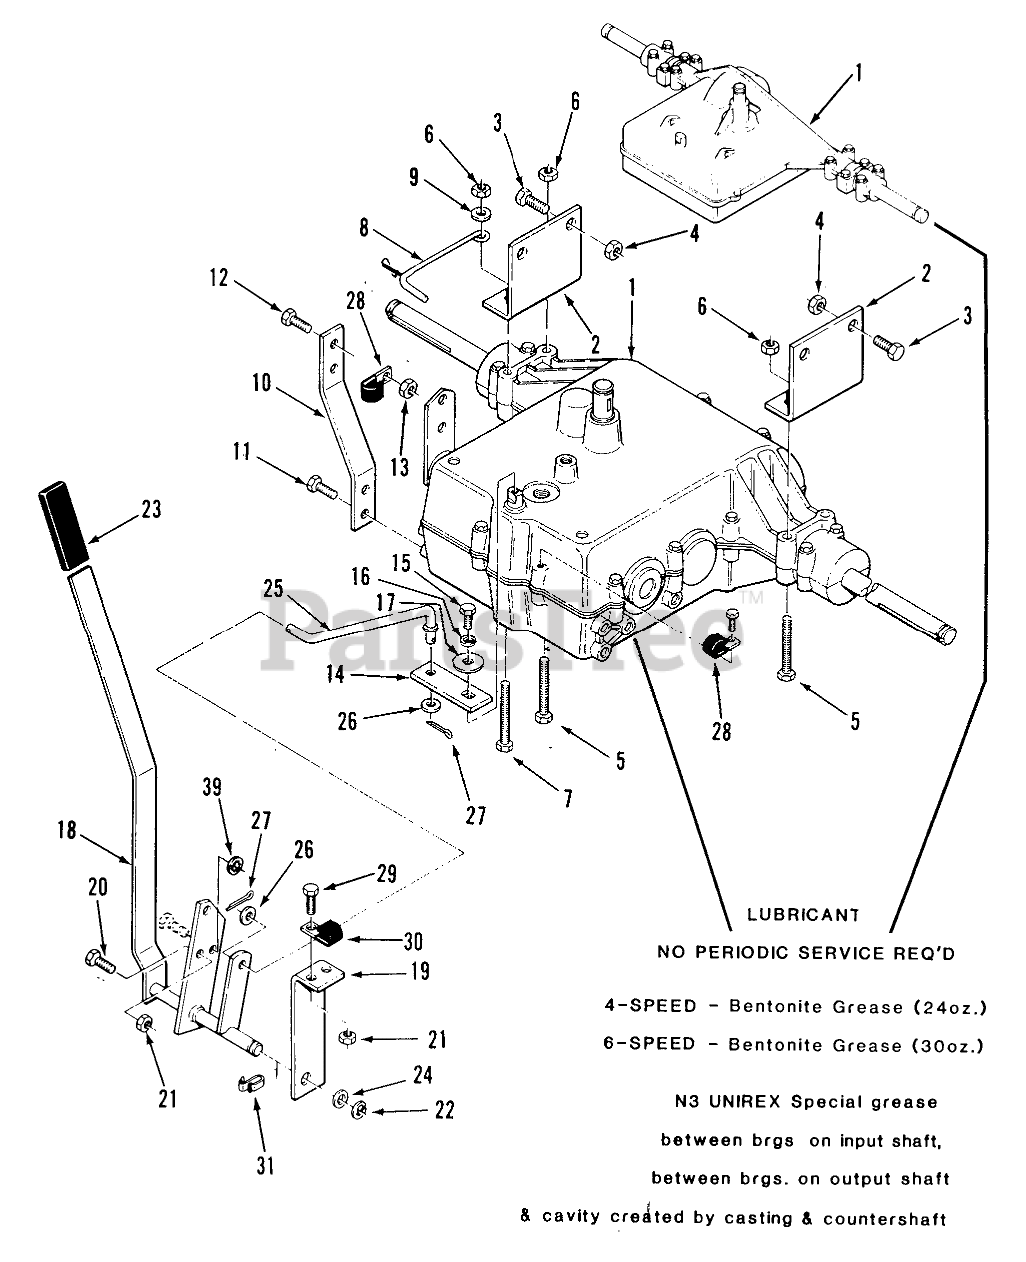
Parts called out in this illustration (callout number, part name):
1	Peerless Transmission (900-028) 110-4 Only
2	Bracket-Rear Axle
3	BOLR HWH 3/8-16X7/8
4	NUT
5	HHCS
6	Nut
7	Pin-Cotter
8	STOP BRAKE
9	WASHER 5/16 SAE
10	STRAP TORQUE
11	Screw
12	Bolt
13	Nut
14	LEVER LOWER SHIFT
15	Bolt 1/4-28 X 7/8
16	Washer
17	WASHER
18	ASSY LEVER SHIFT R
19	SUPPORT SHIFT
20	Bolt
21	Nut
22	E Ring
24	Washer
25	ROD SHIFT LOWER
26	WASHER 5/16 SAE
27	Cotter Pin
28	J-CLIP
29	BOLT 5/16-18 X 3/4
30	J-CLIP
31	CLIP-CABLE
39	Washer-Lock
